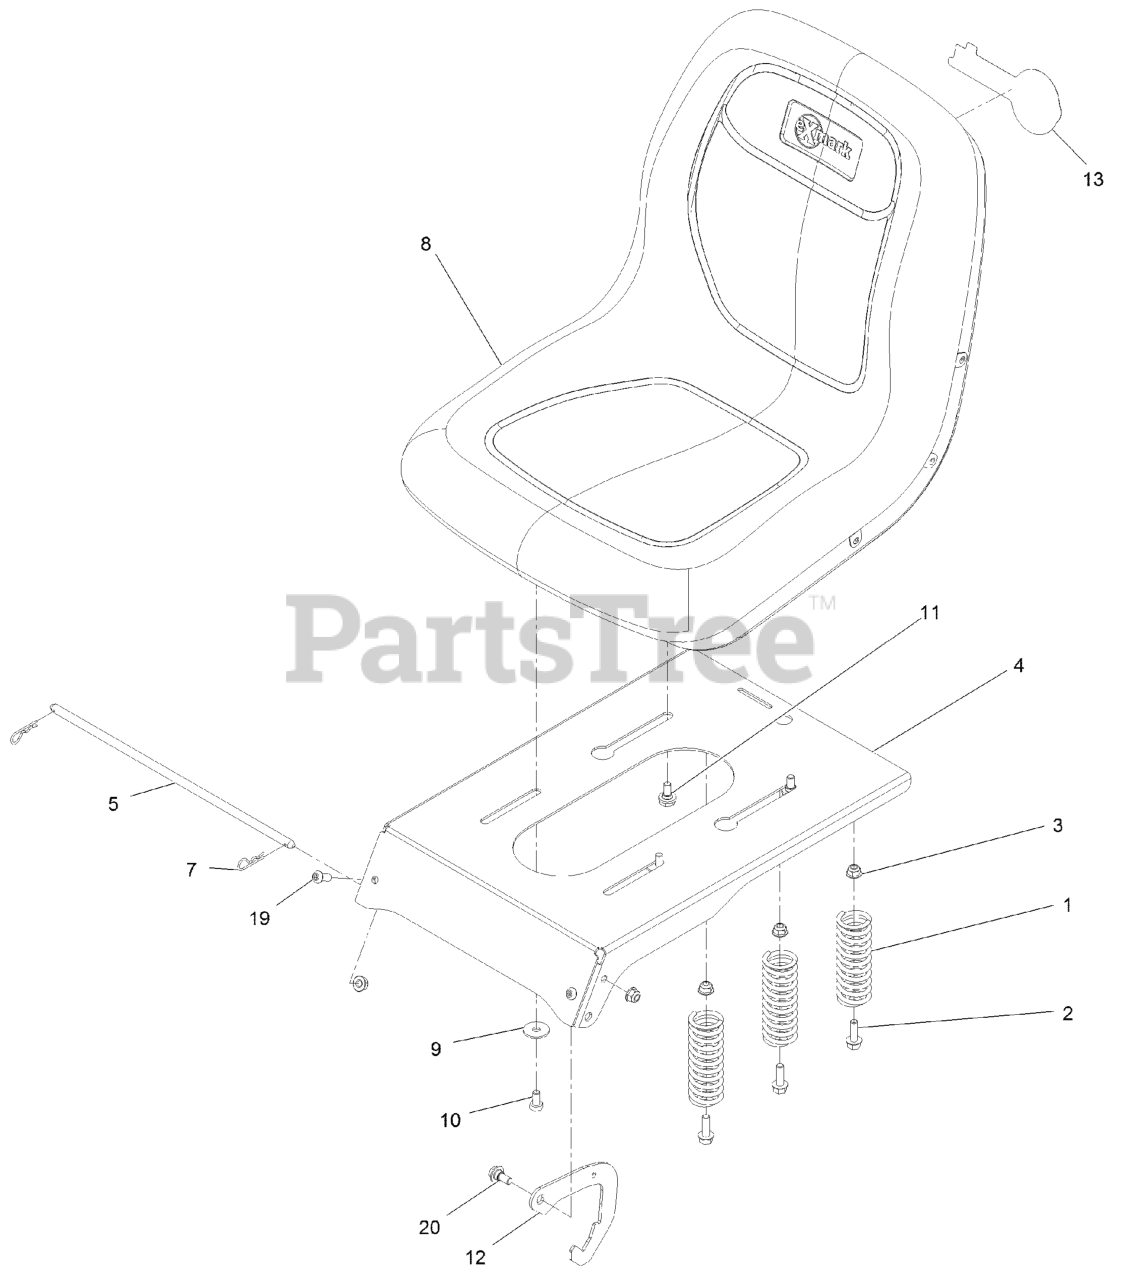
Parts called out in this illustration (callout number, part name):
1	SPRING-COMPRESSION
2	SCREW-HHF
3	NUT-HF, NI
5	Rod-Pivot, Narrow
7	PIN-COTTER
8	SEAT-18 IN
9	WASHER-PIVOT
10	SCREW-HH
11	BOLT-SHOULDER,HFH
12	Seat Latch
13	DECAL-EXMARK LOGO
19	SCREW-HSBH
20	SCREW-SHOULDER
